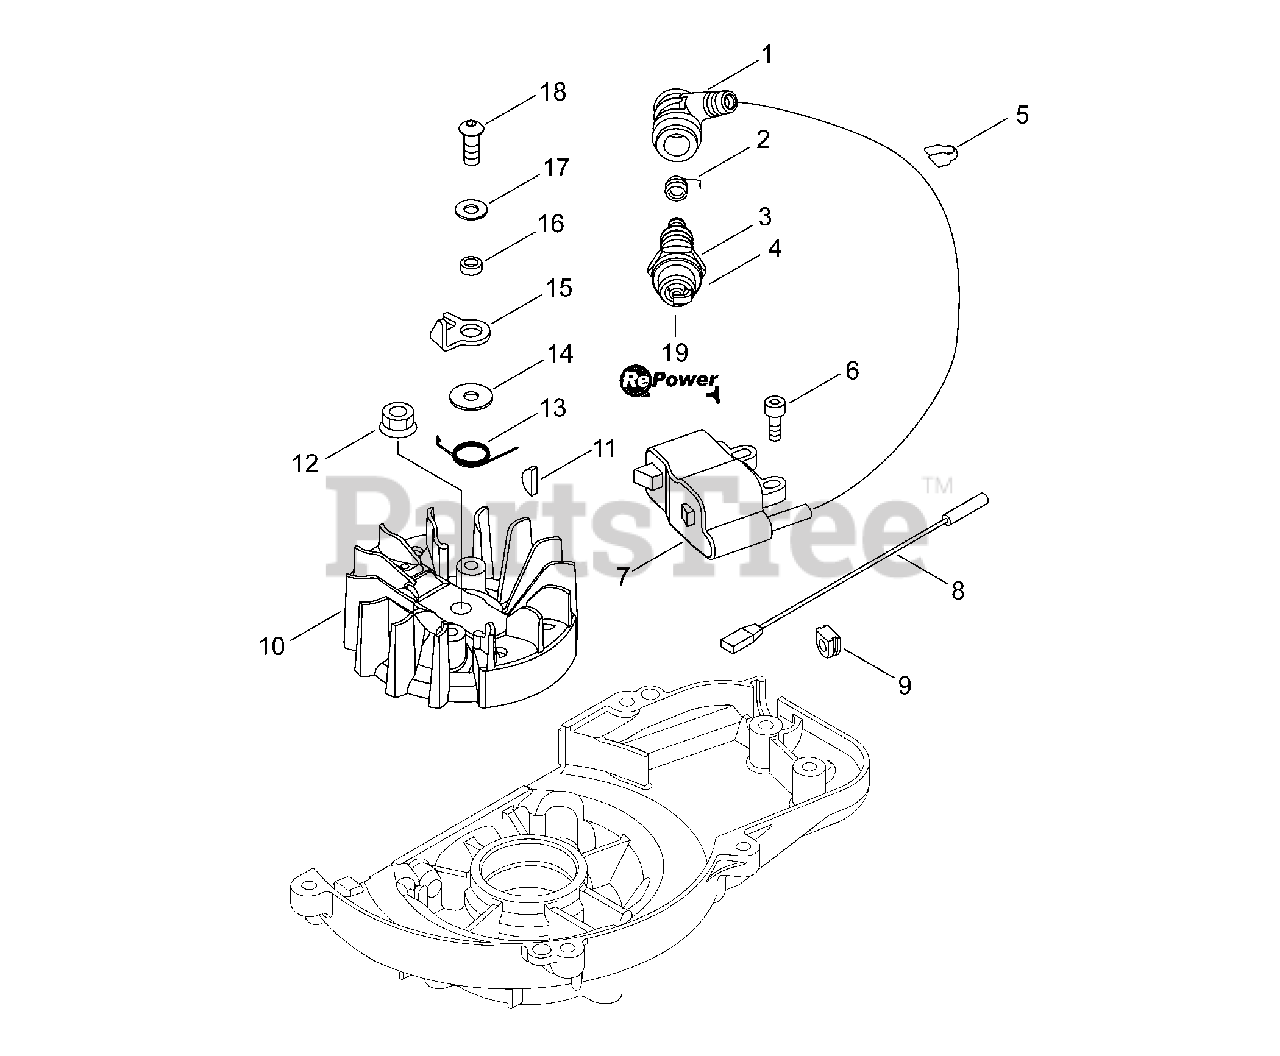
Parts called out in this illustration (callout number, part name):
1	CAP, SPARK PLUG
2	TERMINAL,SPARKPLUG
3	PLUG, SPARK BPM8Y
4	PLUG, SPARK BPMR8Y
5	LABEL,OPERATION
6	BOLT, TORX 4
7	COIL, IGNITION
9	GROMMET,HT CORD
10	ROTOR, MAGNETO
11	KEY, WOODRUFF
12	NUT, FLANGE
13	SPRING,TORSION
17	WASHER 5
19	TUNE-UP KIT - REPOWER
